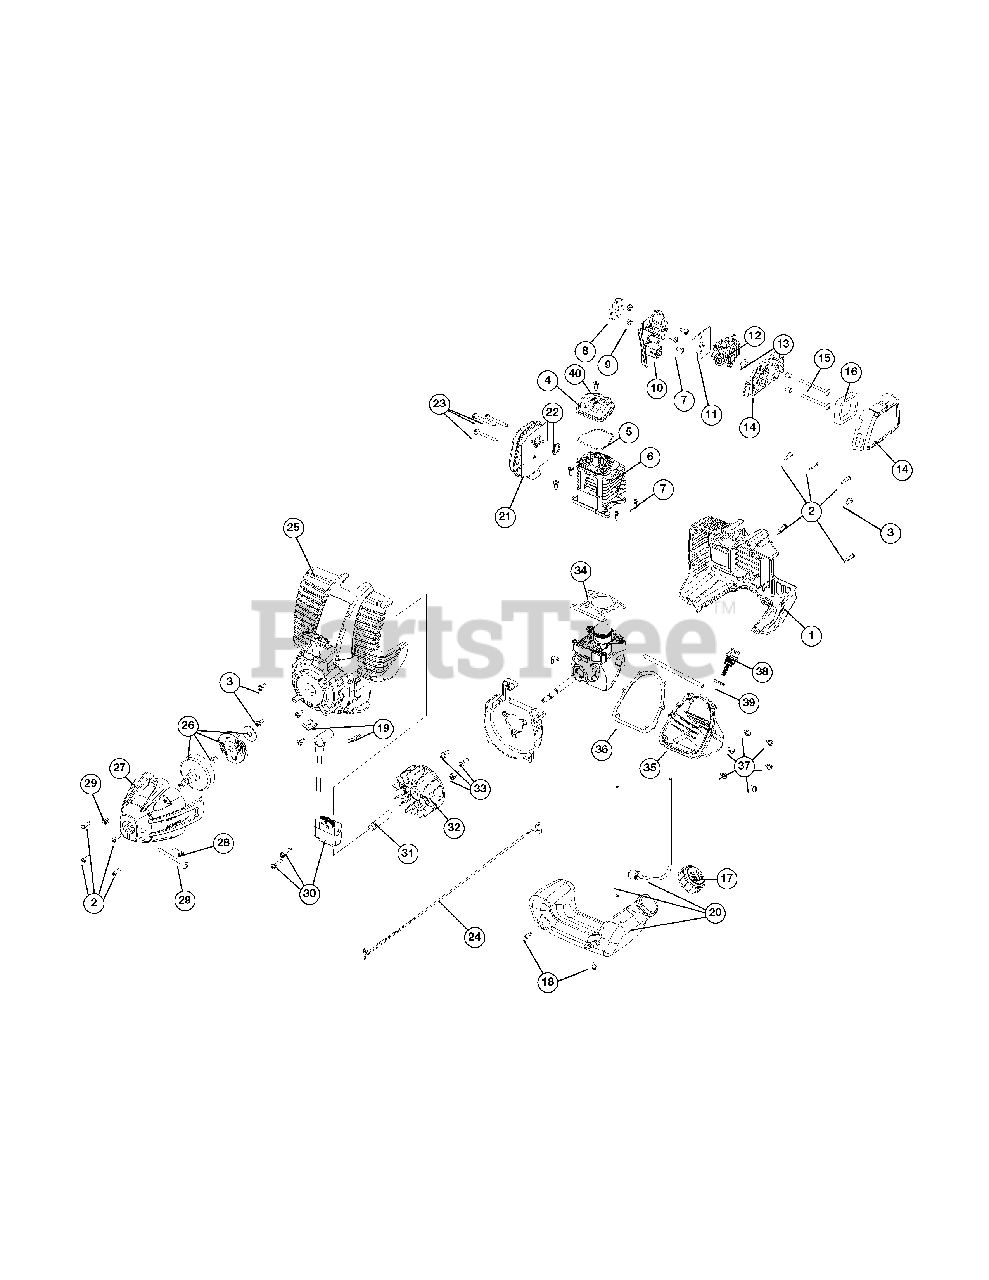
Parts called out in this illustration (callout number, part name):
1	Engine Cover
4	Valve Cover
5	Valve Cover Gasket
6	Cylinder Assembly (Incl. 5, 7 & 34)
7	Cylinder Screw
8	Insulator Gasket
10	Insulator (Incl. 11)
11	Carburetor Gasket
12	Carburetor w/Primer
13	Carburetor O-ring
14	Air Filter Cover Assembly (Incl. 16)
15	Air Filter Mounting Screw
16	Air Filter
20	Fuel Tank Assembly (Incl. 17)
21	Muffler Assembly (Incl. 22 & 23)
22	Muffler Gasket
23	Muffler Mounting Screw
25	Starter Housing Assembly (Incl. 3)
26	Clutch Assembly
26	Clutch Drum Assembly
27	Clutch Cover Assembly (Incl. 2, 28 & 29)
28	Anti-Rotation Screw
29	Clamping Screw Assembly
30	Ignition Module Assembly
33	Shroud Screw
34	Cylinder Gasket
35	Oil Pan (Incl. 36 & 37)
36	Oil Pan Gasket
37	Oil Pan Screw
38	Dipstick Assembly (Incl. 39)
